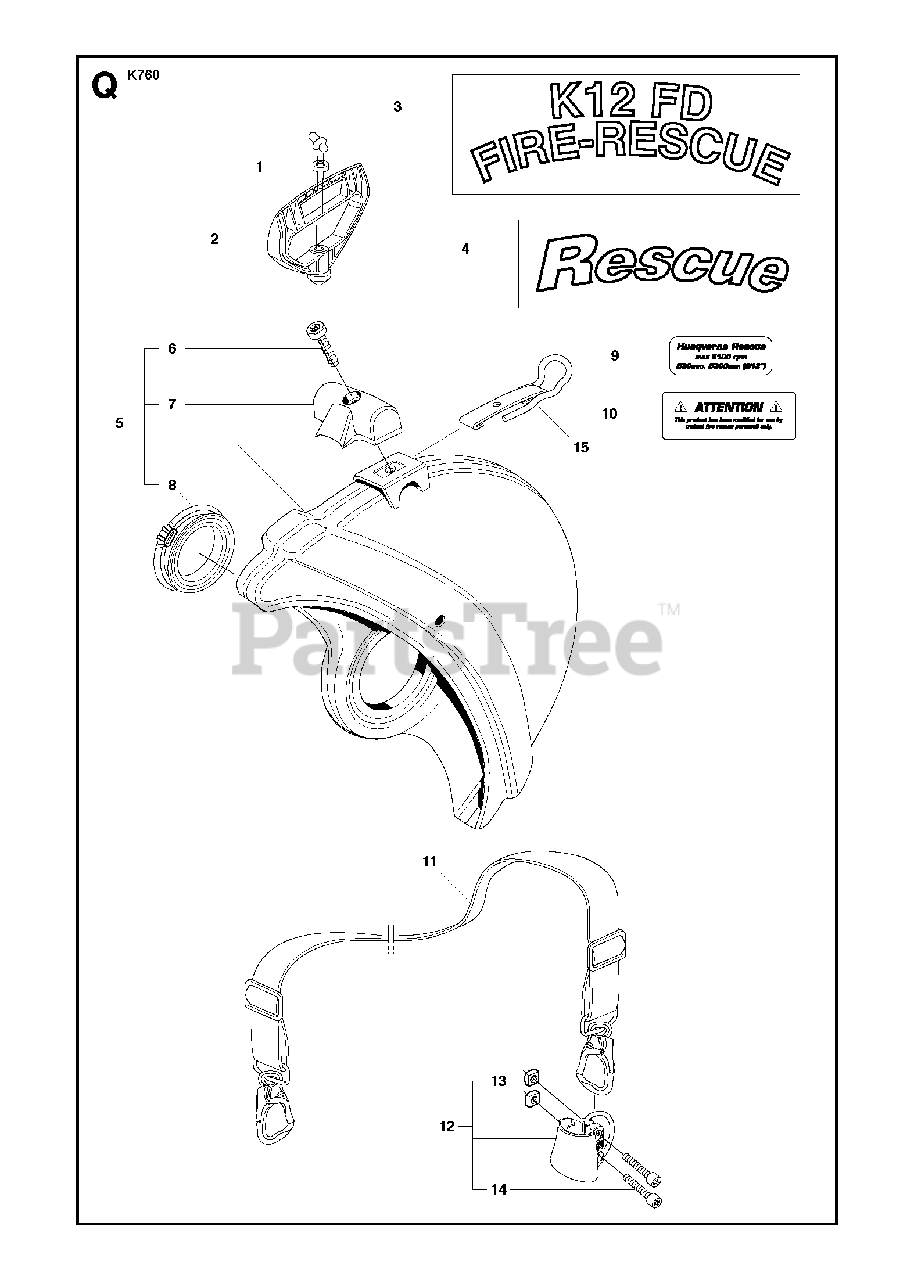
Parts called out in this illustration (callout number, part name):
2	STARTER HANDLE
6	SCREW ITXSCM
14	SCREW ITXSCM
